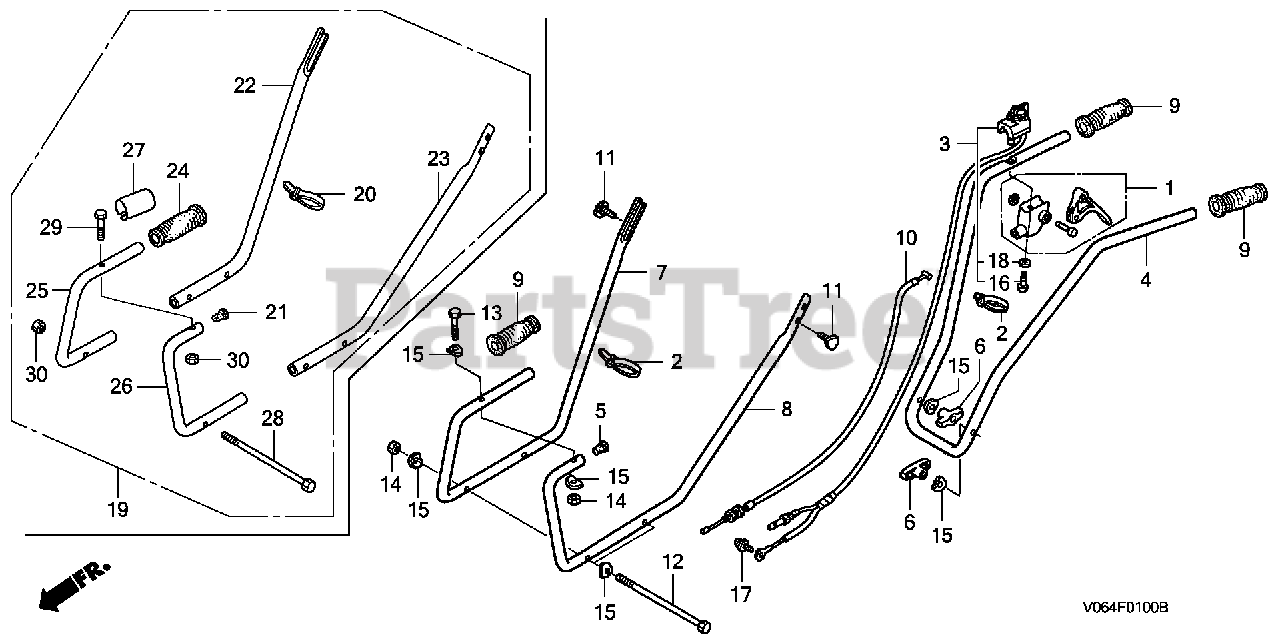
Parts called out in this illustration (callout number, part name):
1	LEVER, THROTTLE
2	TIE, CABLE
3	SWITCH ASSY., ENGINE STOP
4	HANDLE (UPPER)
5	CAP, HANDLE (LOWER)
6	GRIP, HANDLE JOINT
7	HANDLE, R. (LOWER) (N/A: USE 06531-V06-305 CONTAI NING BOTH L. AND R. HANDLES.)
8	HANDLE, L. (LOWER) (N/A: USE 06531-V06-305 CONTAI NING BOTH L. AND R. HANDLES.)
9	GRIP, HANDLE
10	CABLE, MAIN CLUTCH
11	BOLT, HANDLE JOINT
12	SCREW (1/4-20X6)
13	SCREW (1/4-20X7/8)
14	NUT (1/4-20)
15	WASHER, CURVED
16	SCREW, PAN (3X12)
17	SCREW-WASHER (5X12)
18	WASHER, SPRING (3MM)
19	HANDLE KIT
20	TIE, CABLE
21	CAP, HANDLE (LOWER)
22	HANDLE, R. (LOWER)
23	HANDLE, L. (LOWER)
24	GRIP, CARRY
25	HANDLE, R. CARRY
26	HANDLE, L. CARRY
27	MARK, HOLD POSITION (U.S.A. LABEL)
28	SCREW (1/4-20X6)
29	SCREW (1/4-20X2)
30	NUT (1/4-20)
